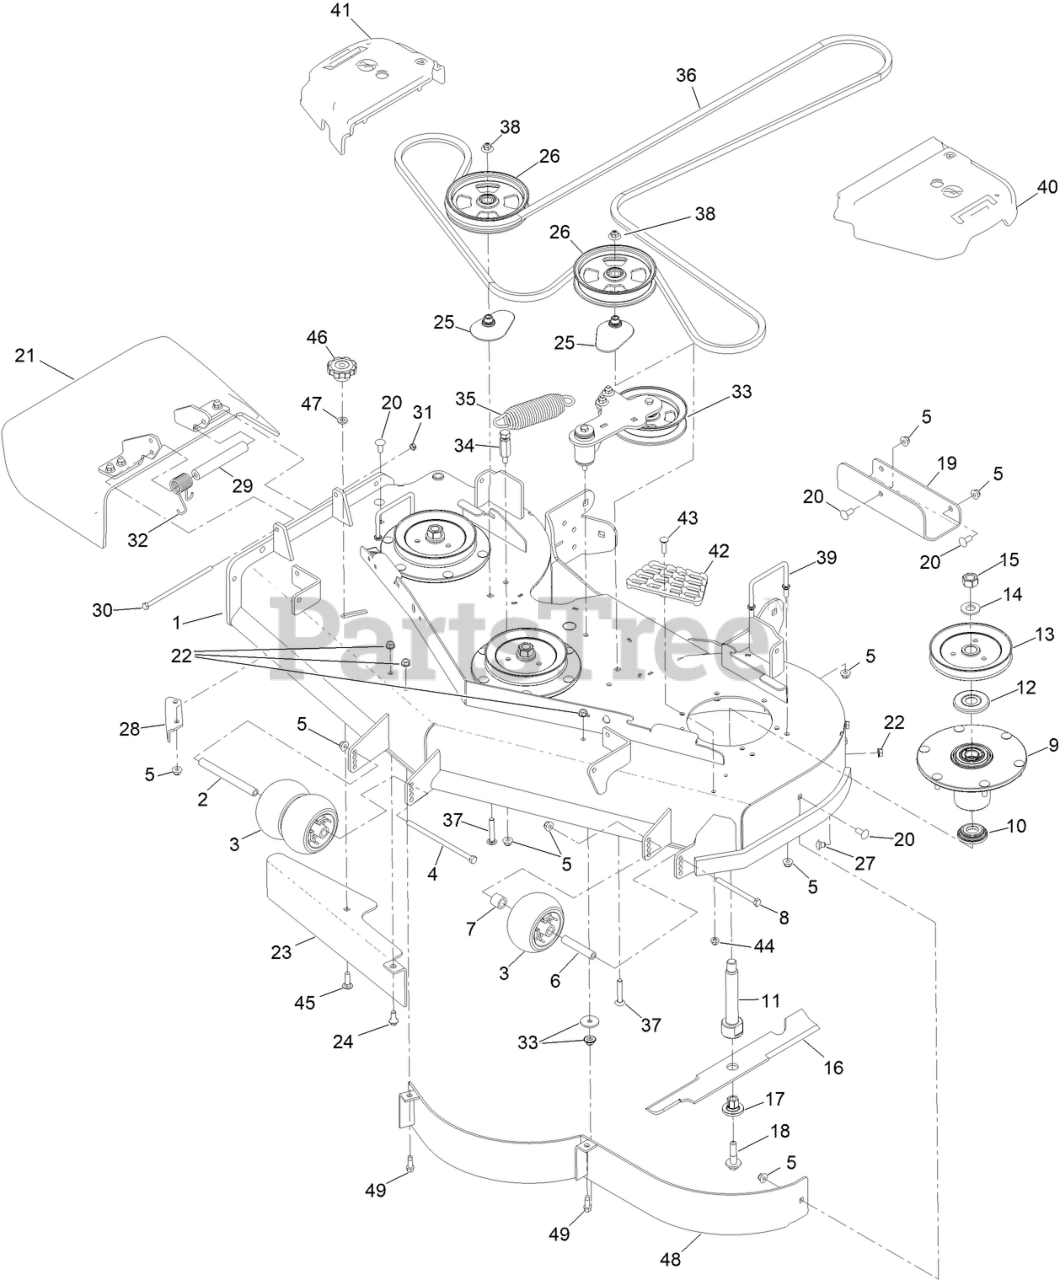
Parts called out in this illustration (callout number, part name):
1	DECK DECAL ASM
2	SPACER-WHEEL
3	ROLLER-SCALP, ANTI
4	SCREW-HH
5	NUT-HF, NI
6	TUBE-SPANNER
7	TUBE-SPACER
8	SCREW-HH
9	SPINDLE ASM
10	GUARD-BOTTOM
11	SHAFT-SPINDLE
12	GUARD-BEARING, TOP
13	SHEAVE-BLADE DRIVE 6.50
14	WASHER
15	NUT-HEX
16	BLADE-FLOW, HIGH
17	BUSHING-HEX
18	SCREW-SEMS
19	PLATE-SKID
20	SCREW-CARR
21	RUBBER DEFLECTOR ASM
22	NUT-HHF, WHIZ
23	PLATE-BAFFLE, FORMED
24	BOLT-SHOULDER
25	SPACER-PULLEY
26	PULLEY-IDLER, FLAT
27	SCREW-CARR
28	BAFFLE-DISCHARGE
29	SPACER
30	SCREW-HH
31	NUT-LOCK, NI
32	SPRING-TORSION
33	IDLER ARM ASM
34	ANCHOR-SPRING, TALL
35	SPRING-EXTENSION
36	BELT-V
37	BOLT-CARR, SHORT NECK
38	NUT-FLANGE, NI
39	WIREFORM-COVER
40	COVER-BELT, LH
41	COVER-BELT, RH
42	STEP-DECK
43	SCREW-CARR
44	NUT-HF, NI
45	BOLT-CARR
47	WASHER-HARDENED
48	BAFFLE ASM
